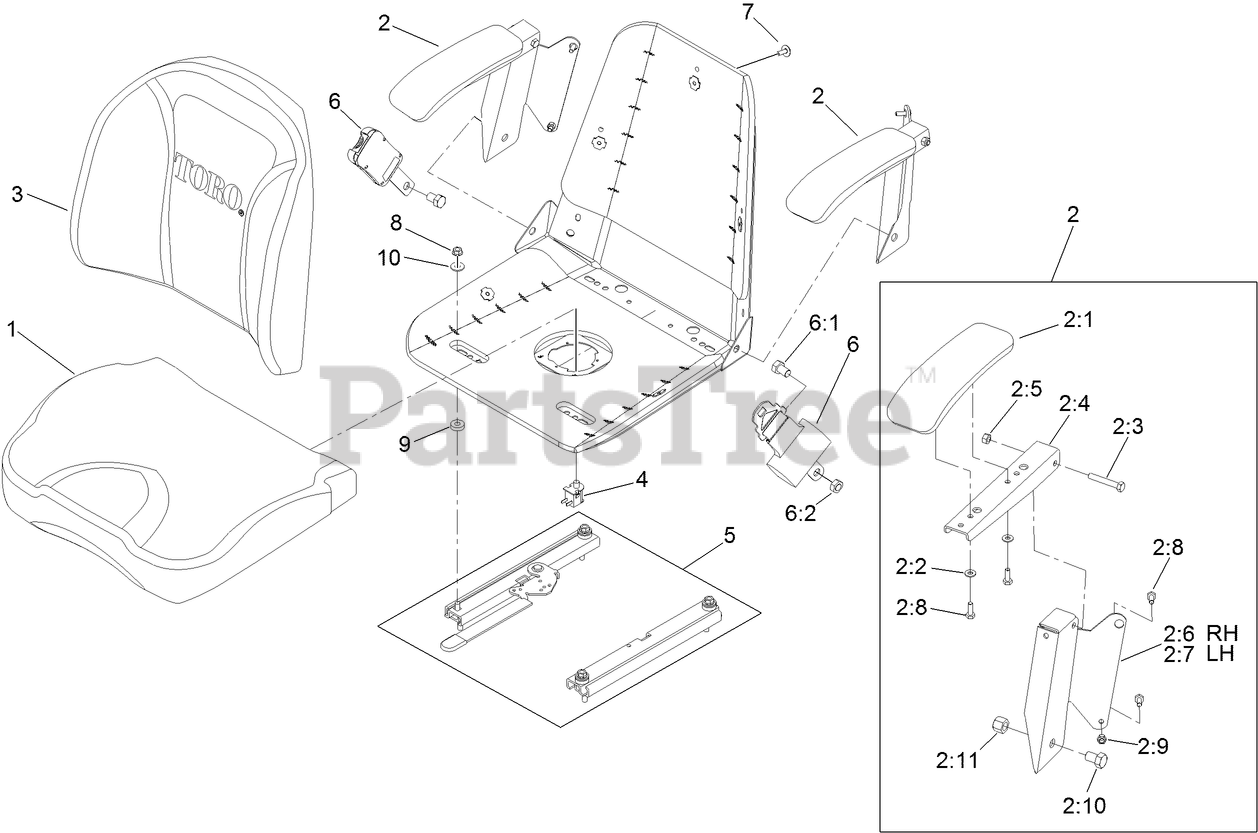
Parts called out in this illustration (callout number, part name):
1	CUSHION-SEAT, BOTTOM
2	ARMREST KIT
2:1	CUSHION-REST, ARM
2:2	WASHER-FLAT
2:3	SCREW-HH
2:4	CHANNEL-ARMREST
2:5	NUT-HEX, SIDE DEFORM
2:6	Bracket-Armrest, RH
2:7	Bracket-Armrest, LH
2:8	SCREW-HH
2:9	NUT-LOCK, NI
2:10	SCREW-HH
2:11	NUT-LOCK, NI
3	CUSHION-SEAT, BACK
4	SWITCH-BAIL
5	TRACK-SEAT
6	SEAT BELT KIT
6:1	SCREW-HH
6:2	NUT-LOCK, NI
7	BOLT-SEAT
8	NUT-HF
9	SPACER-PIN, MOUNTING
10	WASHER-FLAT
